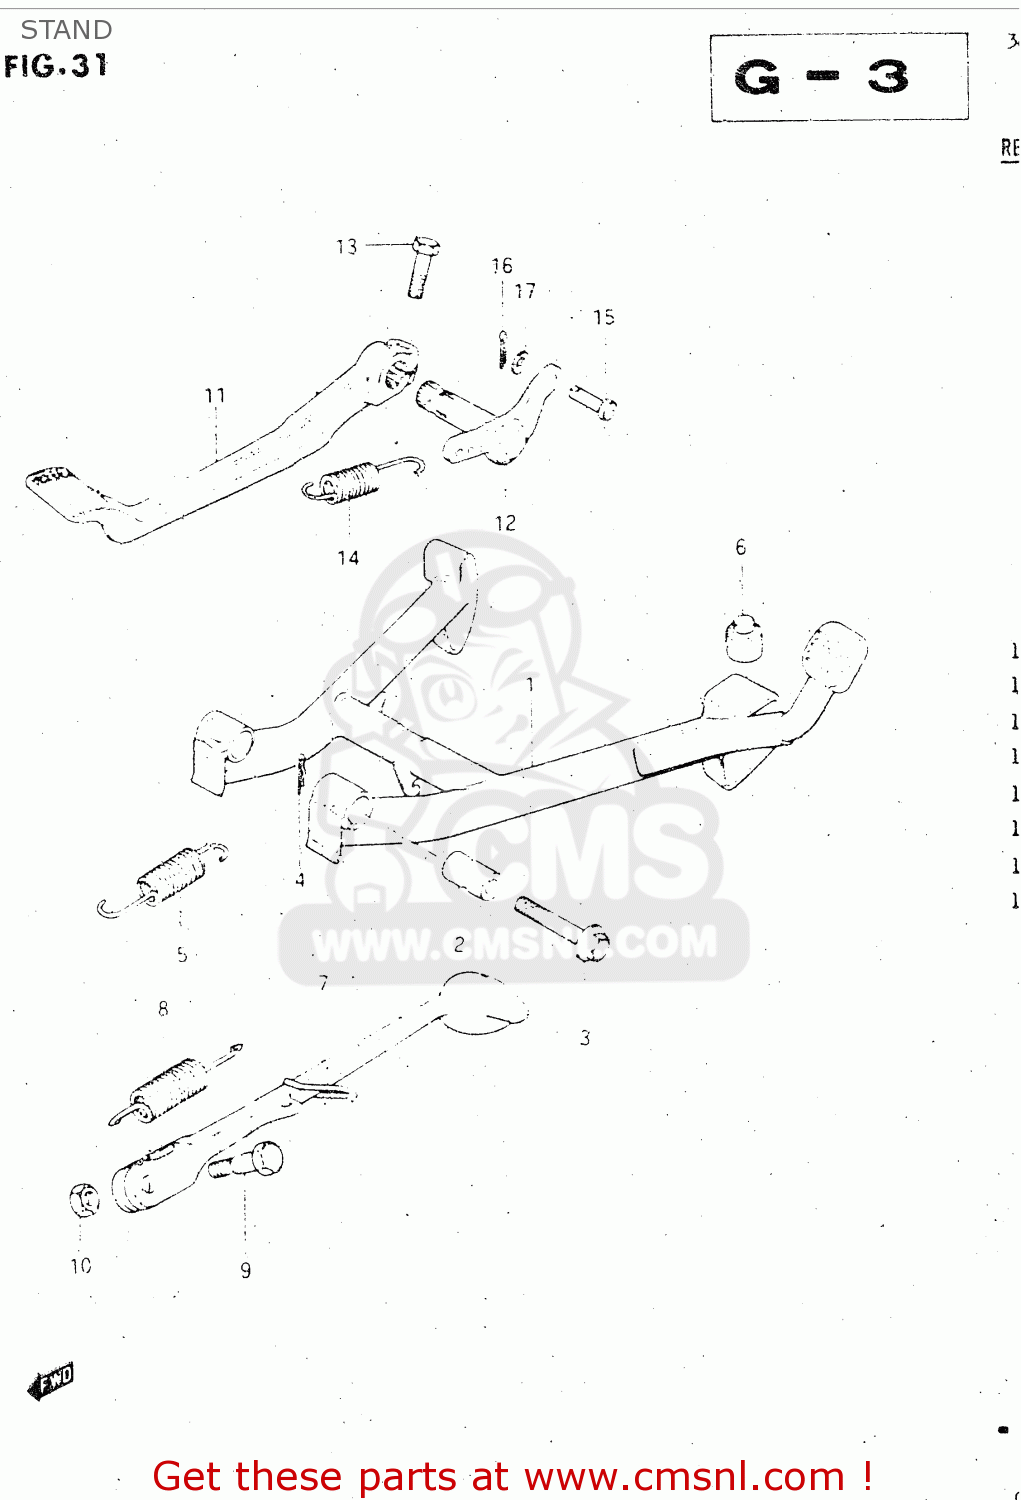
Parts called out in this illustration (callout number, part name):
1	STAND,CENTER
2	SPACER (10.5X16X31.8)
3	BOLT 10X50
4	CLIP
5	SPRING
6	CUSHION
7	STAND,SIDE
8	SPRING
9	BOLT L:30
10	NUTM10X1.25X8
11	PEDAL,BRAKE
12	ARM,BRAKE PEDAL ROD
13	BOLT
14	SPRING
15	PIN
16	PIN
17	WASHER
